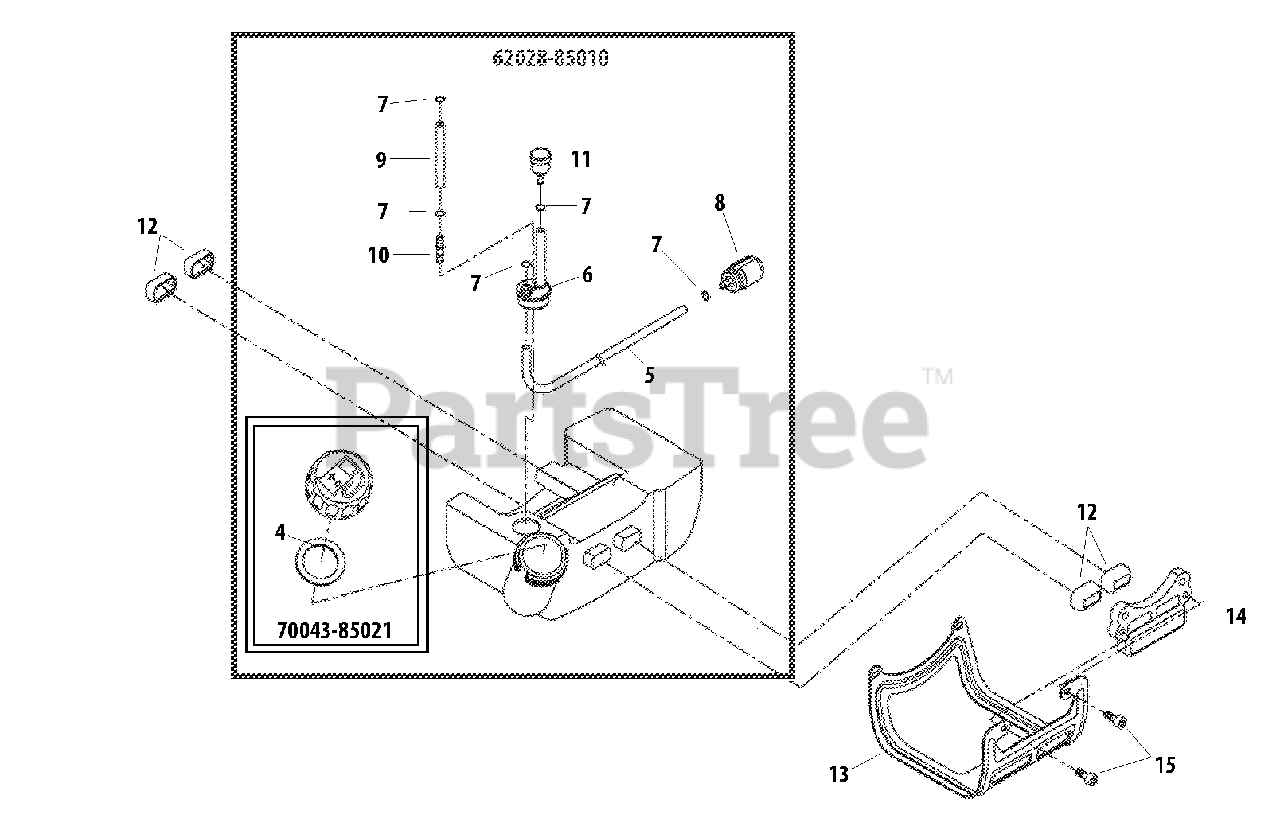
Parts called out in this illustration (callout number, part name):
4	GASKET, CAP
5	PIPE - FUEL
6	GROMMET
7	RING, RETAINING - 6
8	FILTER, FUEL
9	PIPE
10	CONNECTOR, PIPE
11	VENT, FUEL TANK
12	CUSHION, TANK
13	GUARD, FUEL TANK
14	BRACKET, FUEL TANK
15	SCREW - 5X12
62028-85010	FUEL TANK ASSY
70043-85201	CAP ASSY
